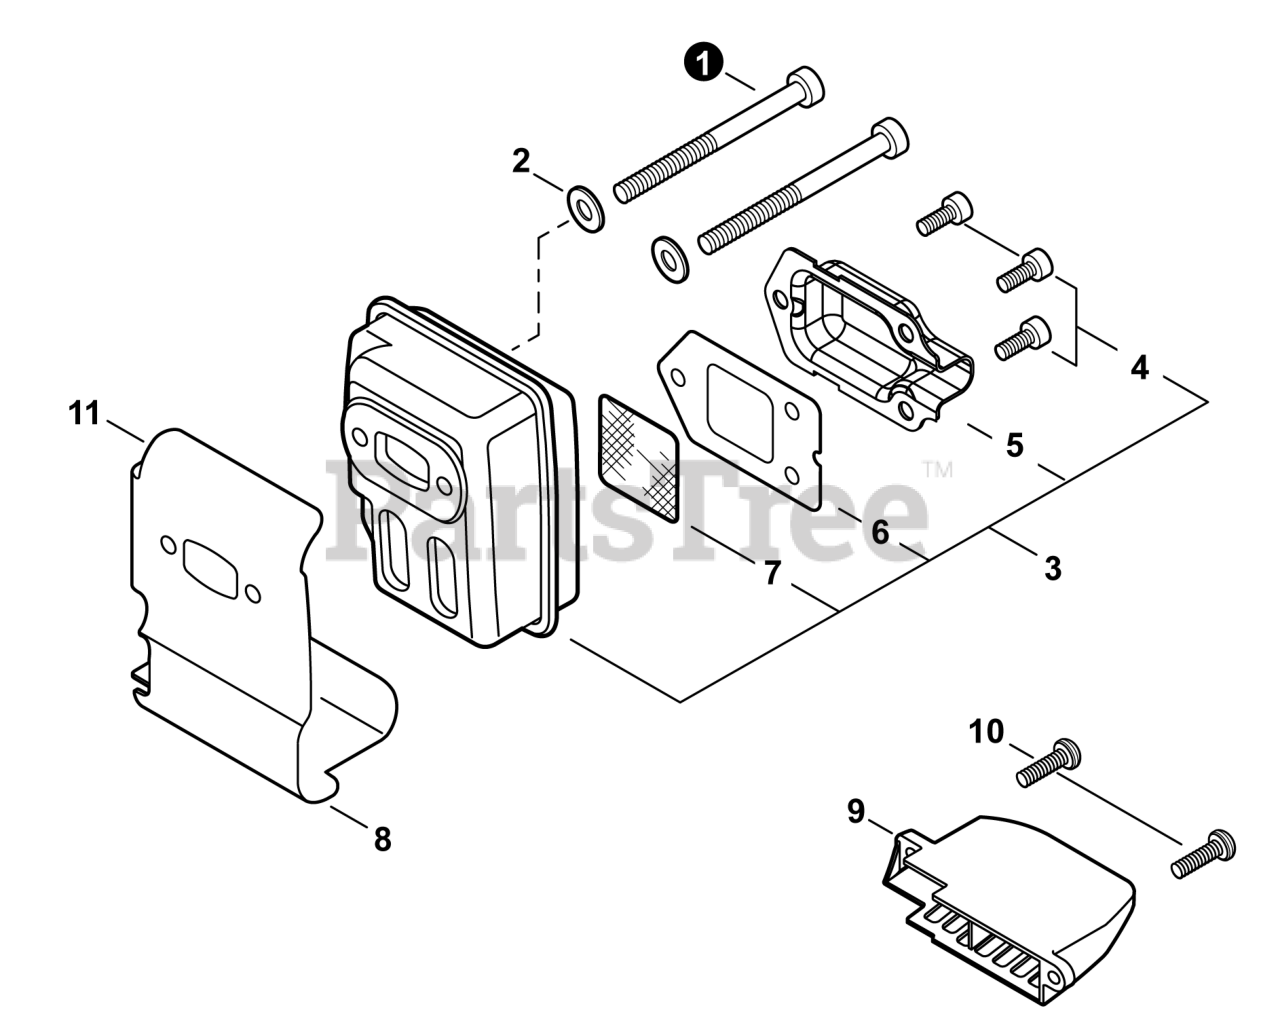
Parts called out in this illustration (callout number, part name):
1	BOLT, TORX 5x55
2	WASHER, FLAT 5.5x10x0.8
3	MUFFLER ASSY
4	BOLT, TORX 4x8
5	GUIDE, EXHAUST
6	GASKET, EXHAUST
7	SCREEN, SPARK ARRESTER
8	HEAT SHIELD, EXHAUST
9	COVER, MUFFLER
10	BOLT, TORX 5x16
11	GASKET KIT: ENGINE, INTAKE, EXHAUST
